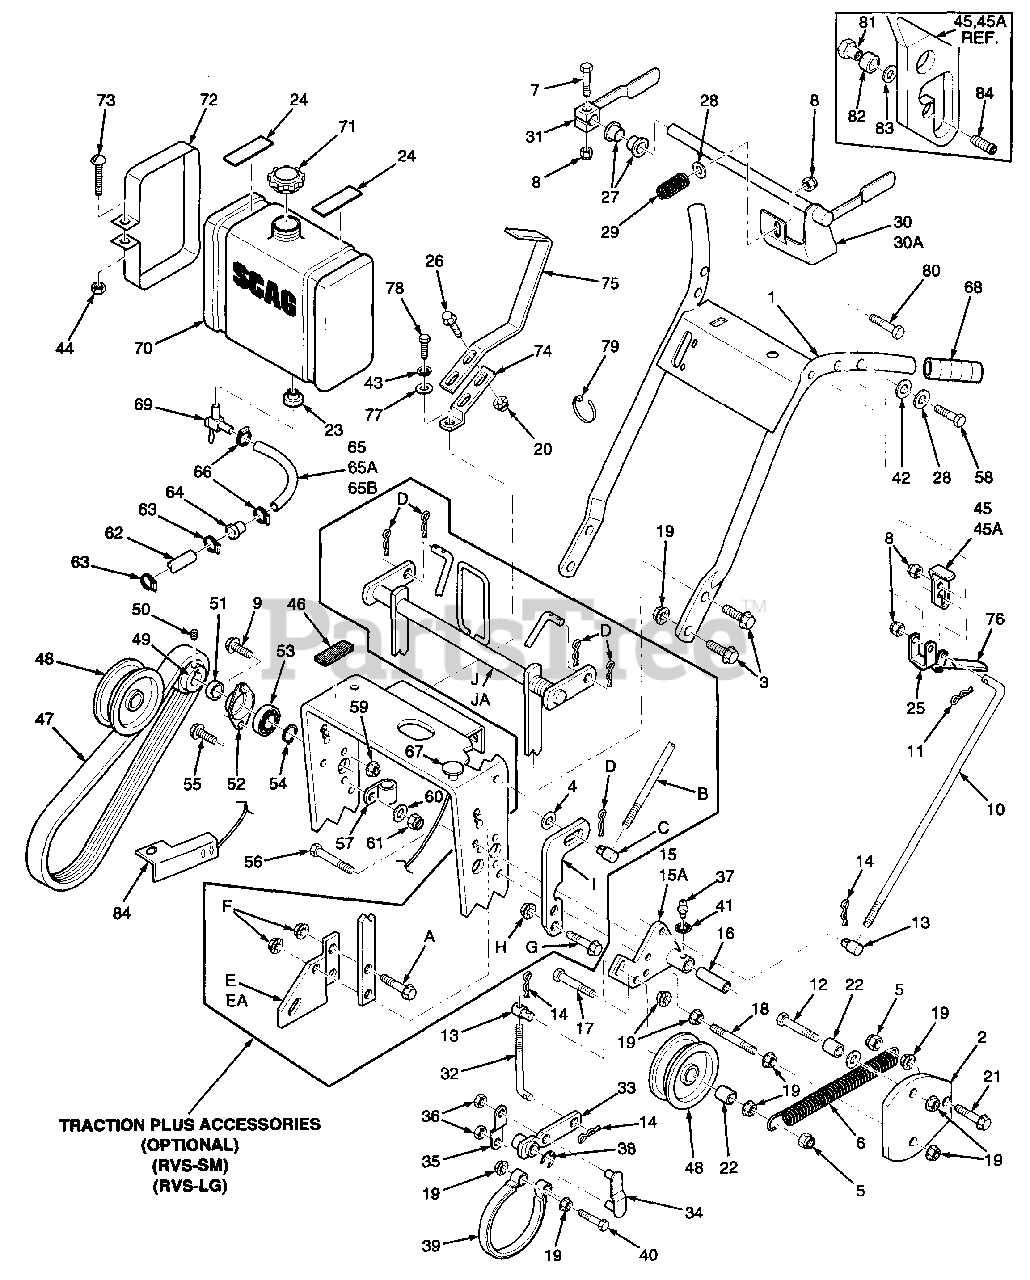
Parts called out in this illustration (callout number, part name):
1	Handle Assembly (Fits SW 36,48)
1	Handle Assembly (Fits SW52,61,72)
2	Belt Guard
3	Capscrw, 3/8-16 x 1" Ser. Flange
4	Washer, 3/8" (.391 x .938 x .105)
5	Nut, 3/8-16 Elastic Stop
6	Spring, Idler
7	Bolt, 5/16-18 x 1-1/4" Hex Head
8	Nut, 5/16-18 Elastic Stop
9	Capscrew, 1/4-20 x 3/4" Hex Head
10	Control Rod, Steering
11	Hair Pin, Small
12	Bolt, 3/8-16 x 4-1/2" Hex Head
13	Swivel Joint
14	Hair Pin, Large .094 Diameter
15	Idler Bracket, RH
15A	Idler Bracket, LH
16	Idler Sleeve
17	Bolt, 3/8-16 x 3/4" Hex Head
18	Support Belt Guard
19	Nut, 3/8-16 Serrated Flange
20	Nut, 5/16-18 Serrated Flange
21	Cpscrw, 3/16-18 x 1-1/4" Ser. Flng.
22	Spacer
23	Bushing
24	Rubber Pad, (Upper)
25	Steering Lever
26	Capscrew, 5/16-18 x 1" Ser. Flng.
27	Bushing
28	Washer, 5/16 (.375 x .875 x .083)
29	Spring, Operator Presence
30	Operator Presence Lever, LH (Small Frame)
30A	Operator Presence Lever, LH (Large Frame)
31	Operator Presence Lever, RH
32	Brake Rod
33	Brake Lever
34	Brake Link
35	Brake Link Plate
36	Nut, 3/8 Push-on
37	Greese Fitting, Straight 1/4-28
38	Retaining Ring, 5/8 Ext. "E"
39	Brake Band
40	Bolt, 3/8-16 x 2" Hex Head
41	1/4" Internal Tooth Lockwasher
42	Curved Spring Washer
43	Socket Head Capscrew #8-32 x 1/2"
44	Nut, 1/4-20 Hex
45	Neutral Latch, RH
45A	Neutral Latch, LH
46	Rubber Pad (Lower)
47	Belt, Wheel Drive
48	Idler Pulley, Wheel Drive
49	Pulley, Jackshaft (Inc. 50)
50	Setscrew, Hex Socket Knurl Cup Pt. 5/16-18 (nylock)
51	Spacer, Jackshaft Pulley
52	Flange, Jackshaft Bearing
53	Bearing, Jackshaft
54	Retaining Ring, 5/8 Ext. Basic
55	Capscrew, 1/4-20 x 1" Ser. Flange
58	Bolt, 5/16-18 x 2" Hex Head
59	Nut, 1/4-20 Serrated Flange
60	Flatwasher, 5/16 (.375 x .875 x .083)
61	Nut, 1/4-20 Elastic Stop
62	Fuel Hose (Kawasaki Only)
63	Fuel Hose Clamp (Kaw. Only)
64	Fuel Filter (Kawasaki Only)
65	Fuel Hose, 1/4" ID, 10" (KH Only)
65A	Fuel Hose, 1/4" ID, 20" (KA & Briggs)
66	Clamp, Fuel Hose
67	Choke Control
68	Grip, Handle
69	Valve, Fuel Shut Off
70	Fuel Tank Assy. (Incl. Bush. & Val.)
71	Fuel Tank Cap
72	Strap, Fuel Tank
73	Screw, 1/4-20 x 2" Rnd Hd Slotted
74	Shift Lever
75	Shift Lever Extention
76	Grip, Steering Lever
77	Washer, 3/8 (.391 x .938 x .105)
78	Nut, 3/8-24 UNF
79	Cable Tie
80	Bolt, 5/16-18 x 2-1/2"
81	Bushing, Bearing Retainer
82	Bearing
83	Washer, #8-.170 x .375 x .032
A	Capscrew, 3/8-16 x 1" Ser. Flng
B	Rod, Traction Control
C	Swivel Joint
D	Hair Pin, Large .094 Dia.
E	Mounting Brkt. LH Traction Cont.
EA	Mounting Brkt. RH Traction Cont.
F	Nut, 3/8-16 Serrated Flange
G	Capscrew, 5/16-18 x 3/4" Ser. Flg.
H	Nut, 5/16-18 Serrated Flange
I	Traction Lever, LH
J	Traction Lever Wldmnt. (Small Fm.)
JA	Traction Lever Wldmnt. (Large Fm.)
